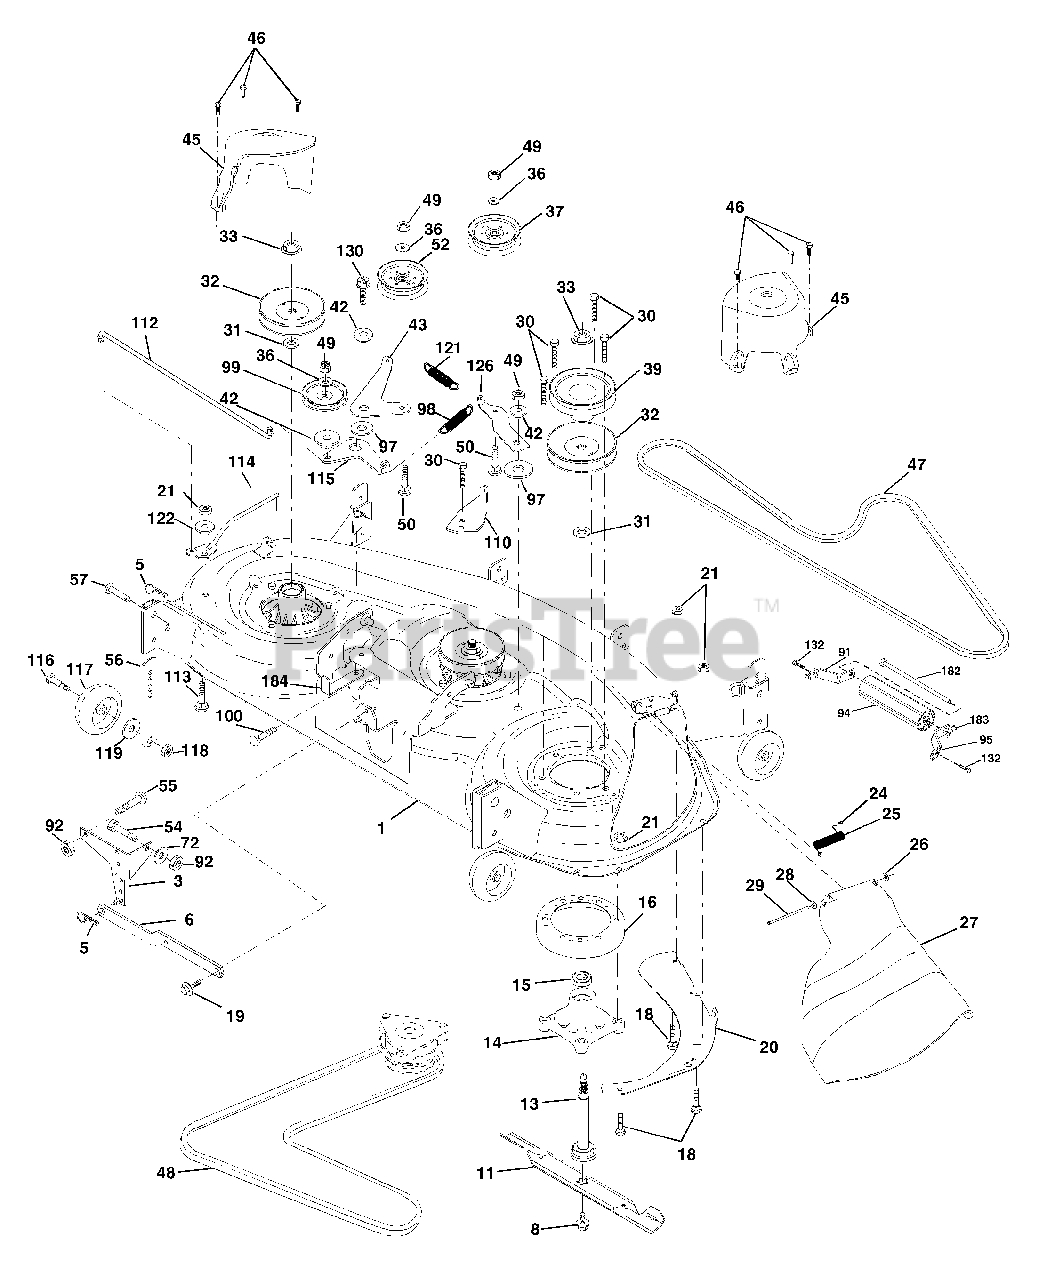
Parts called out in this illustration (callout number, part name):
1	Deck Weldment Mower 48
3	Bracket Asm., Sway Bar
5	Retainer Spring
6	Sway Bar Deck
8	Bolt, 7/16 Asm. Blade
13	Shaft Asm. greaseable
14	Housing Mandrel 48"
15	Bearing, Ball, Mandrel
16	Stripper, Mower
17	Bolt Rdhd Sq Neck 3/8-16 x 1.25
18	Bolt, Carriage 5/16-18 x 5/8
19	Bolt, Hex Head, Shoulder 5/16-18
20	Baffle, Vortex Mower
21	Nut, Crownlock 5/16-18 UNC
24	Cap, Sleeve
25	Spring, Torsion
27	Shield, Deflector Mower
28	Washer 11/32 x 5/8 x 16 Ga.
29	Rod, Hinge
30	Screw, Thdroll, Washer Head
31	Washer, Spacer Mower Vented
32	Pulley, Mandrel
33	Nut, Flg. Top Lock Cntr. 9/16
36	Washer 13/32 x 13/16 x 16 Ga.
37	Pulley, Idler, Flat
39	Pulley, Idler, Driven
42	Spacer, Retainer
43	Arm, Idler Secondary
45	Cover, Mandrel Deck
46	Screw, Thdroll. 1/4-20 x 5/8
47	V-Belt, Mower, Secondary
48	V-Belt, Mower, Primary
49	Nut, Crownlock 3/8-16 UNC
50	Bolt, Carriage 3/8-16 x 1-1/2 Gr. 5
52	Pulley Idler Flat 46 Pri. Drive
54	Bolt Fin Hex 3/8-16 x 1
55	Bolt Rdhd Sqnk 3/8-16 x 1
56	Bar Pnt Adjusting Wheel Gauge
57	Pin Head Rivet
72	Washer 13/32 x 13/16 x 12
91	Bracket, Asm Noseroller, LH 48
92	Nut Lock Hex w/Ins 3/8-16
94	Roller, Nose 48"
95	Bracket, Asm Noseroller RH 48
97	Washer Hardened
98	Spring Primary Drive
99	Pulley Idler "V"
100	Bolt RDHD Sqnk 3/8-16 Unc x 2
107	Baffle Vac Edge Mower
108	Bolt Rdhd 1/4-20 x 1/2
109	Nut Crownlock 1/4-20
110	Arm Spring Secondary
112	Link Tension Relief Lever
113	Bolt Carr. 5/16-18 x 1
114	Tension Asm Relief Lever
115	Arm Spring Tension Relief
116	Bolt, Shoulder
117	Gauge Wheel
118	Nut, Centerlock 3/8-16 UNC
119	Washer 3/8 x 7/8 x 14 Ga.
121	Spring Secondary Drive
122	Bushing Pivot Tension Relief
126	Arm, Idler, Primary Deck
130	Screw 3/8-16 x 1.0
132	Screw 3/8-16 x .75
182	Rod Roller Nose
183	Retainer Spring
184	Keeper Belt Idler
